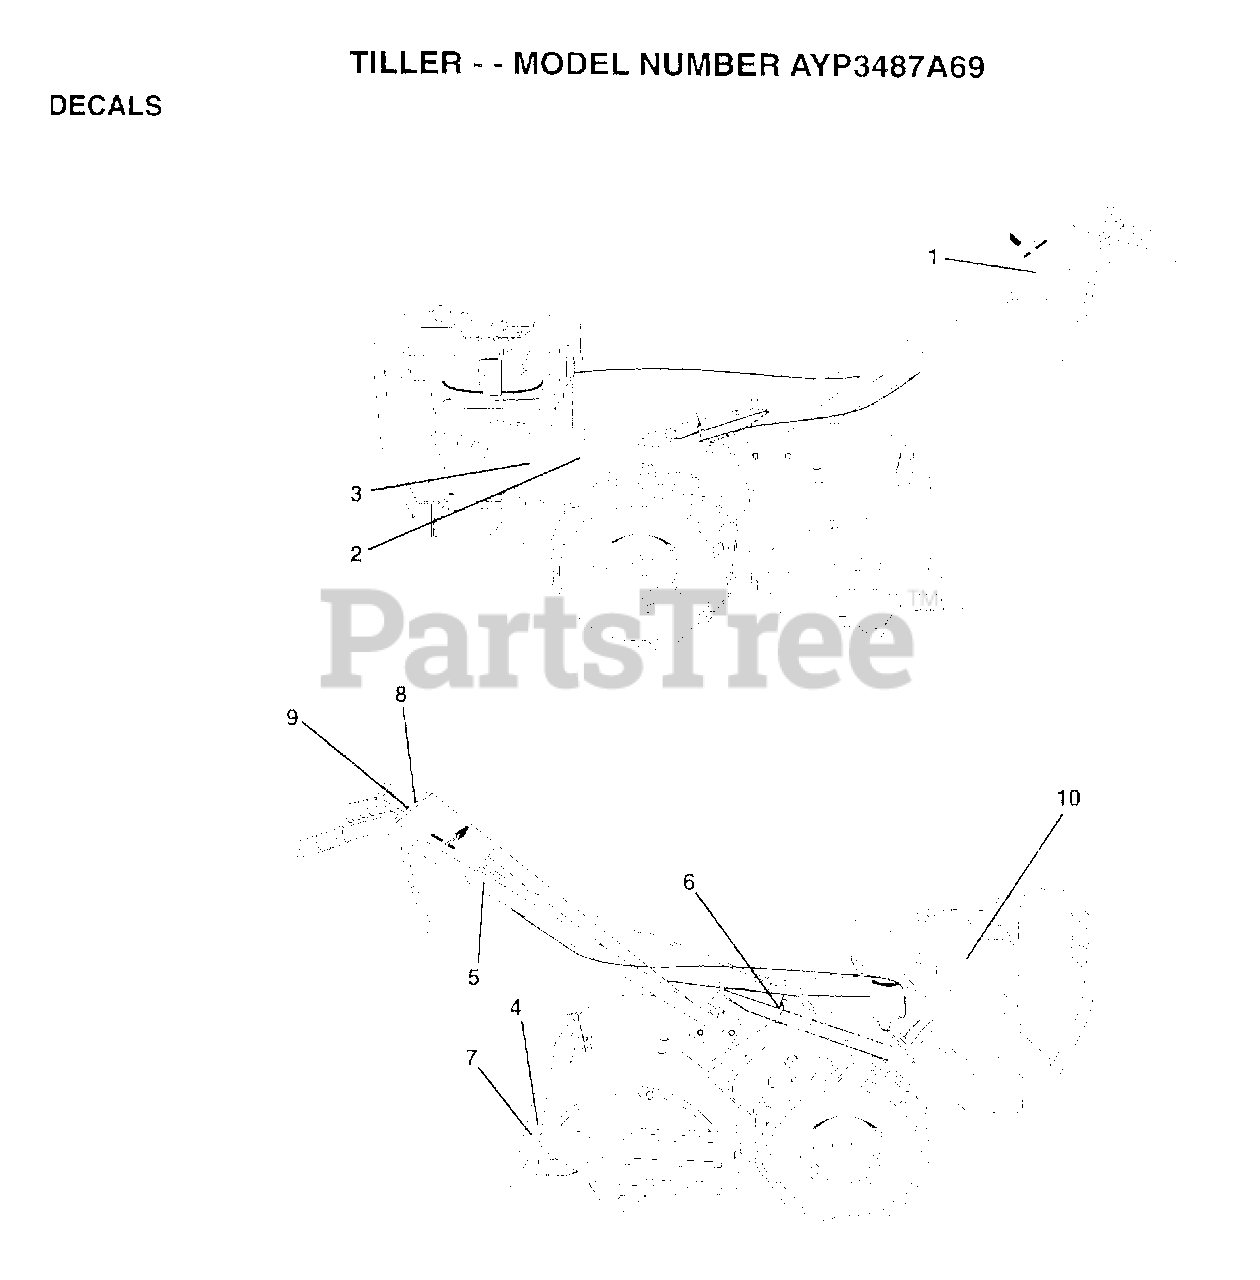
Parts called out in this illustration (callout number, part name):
1	DECAL.CNTL.PNL.WZ
3	DECAL.GUARD.BLT.W
5	DECAL TI
6	DECAL.SHIFT.IND.
7	DECAL TI
10	DECAL, BRIGGS & STRATTON
